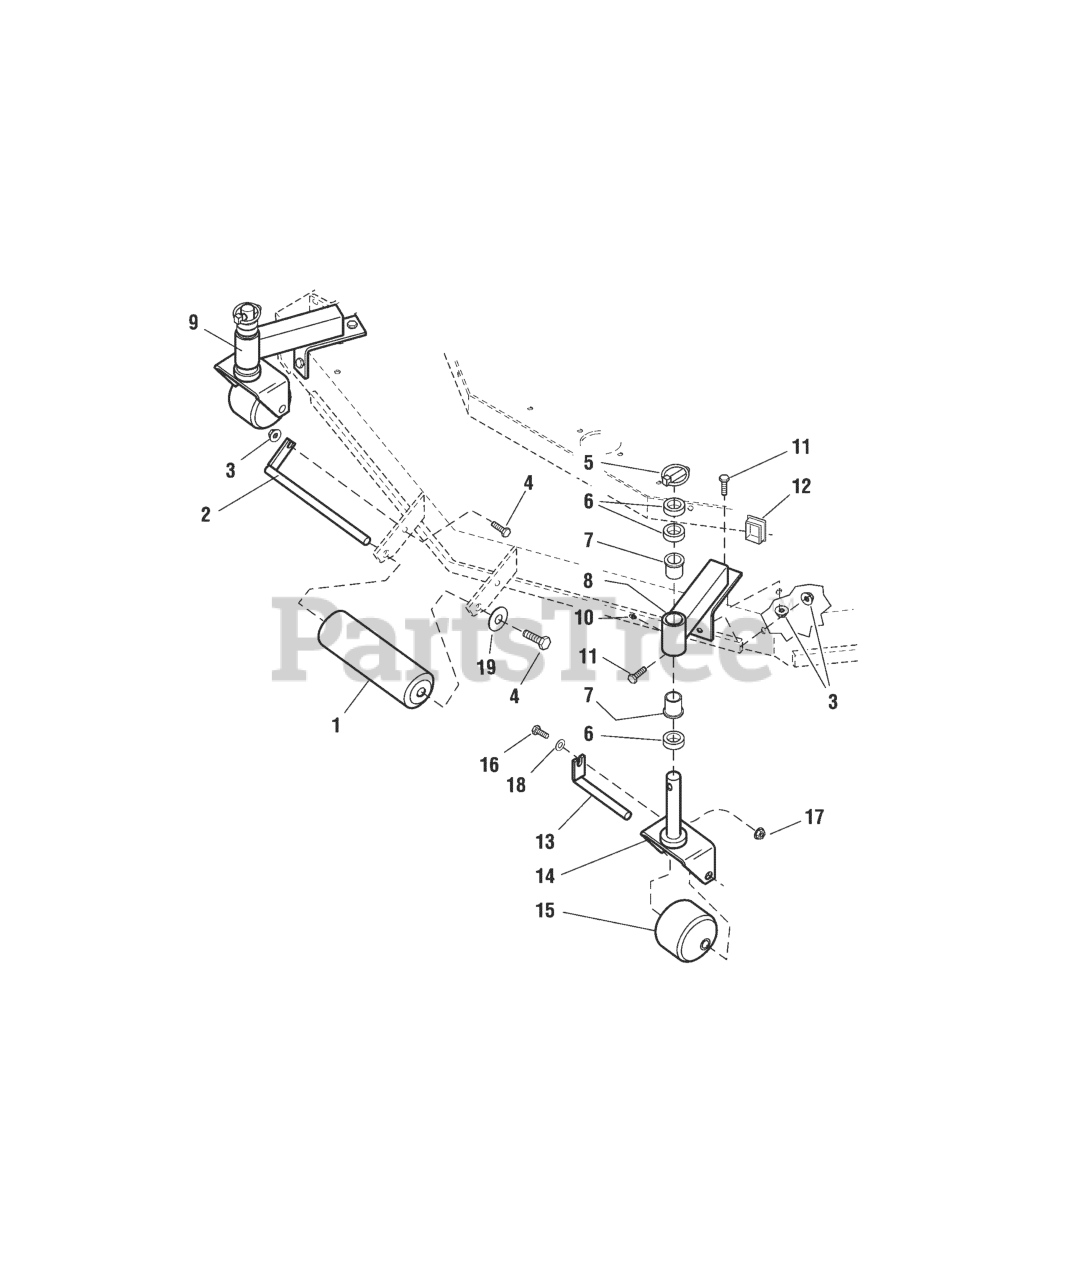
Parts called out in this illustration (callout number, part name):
1	ROLLER
3	NUT, 3/8-16 Hex Serrated Flange
4	BOLT, 3/8-16 X 1" GD5 CZ
5	PIN, Lynch
6	SPACER, 1.02 x 1.56 x .50
7	BUSHING, FLANGE
8	ASSM, ARM, DECK CASTER, LH
9	ASSM, ARM, DECK CASTER, RH
10	GREASE FITTING
11	BOLT, 3/8-16 X 3/4" GD5 CZ
12	CAP, Plastic
13	CASTER ROLLER PIN
14	CASTER YOKE
15	ROLLER, Caster
16	BOLT, 5/16-18 X 3/4 GD5
17	NUT, 5/16-18 HEX SERRATED FLANGE (SMALL)
18	WASHER, 5/16" GD9
19	WASHER, .390 X 1.50 X .109 YZ
